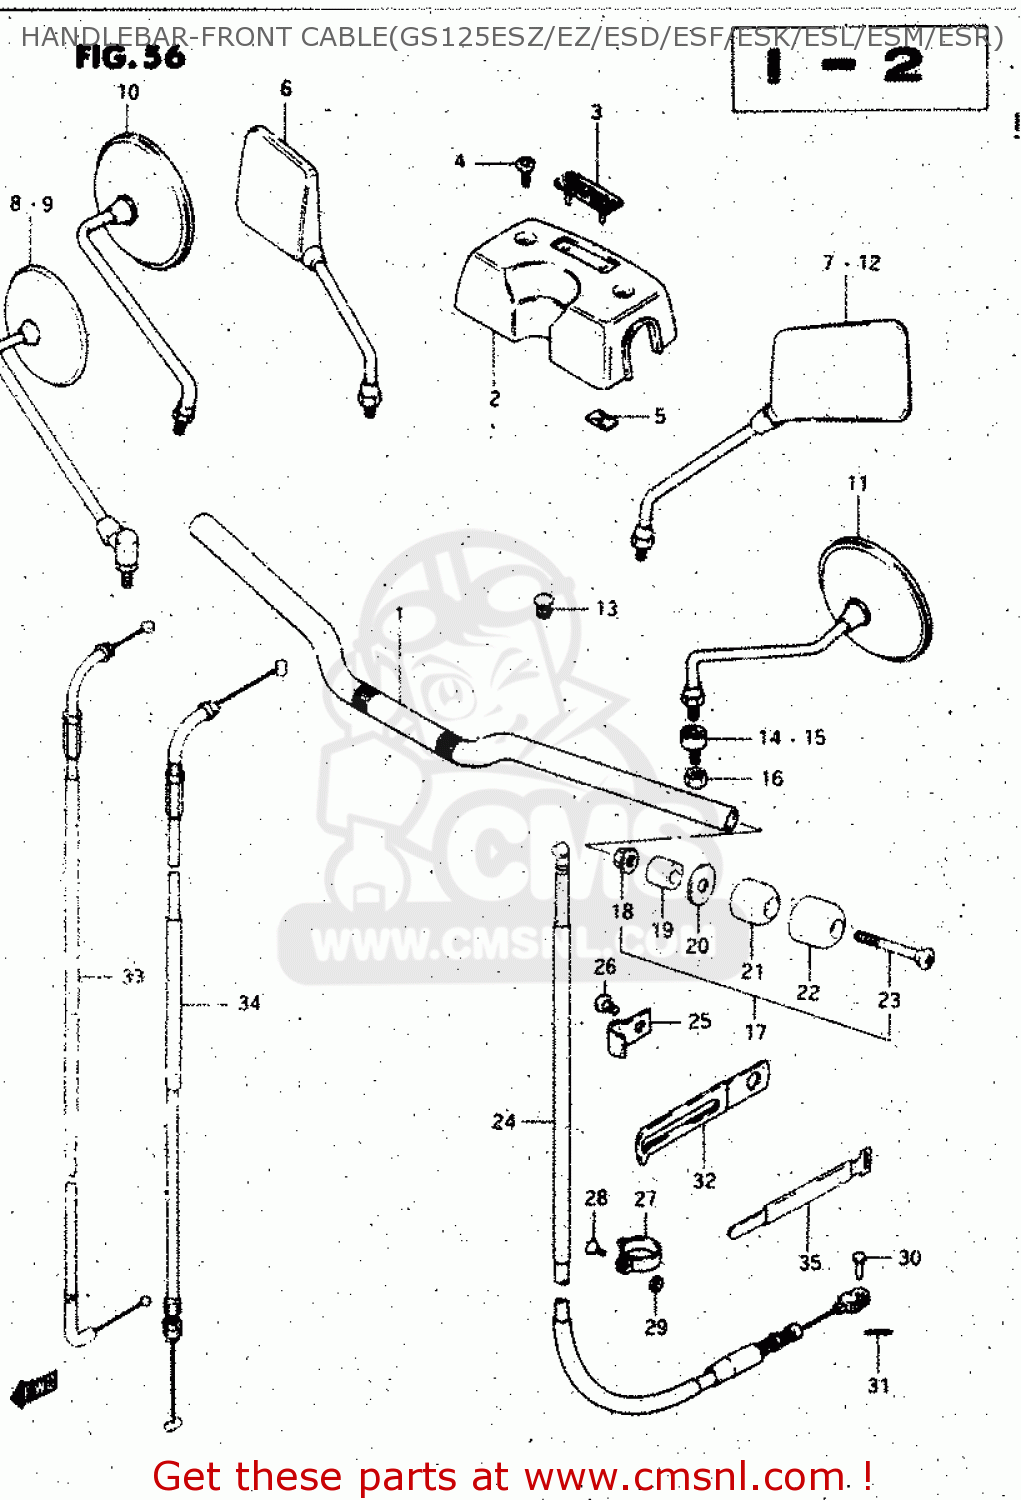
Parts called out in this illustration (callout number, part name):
1	HANDLEBAR
2	COVER,STEERING HEAD
3	EMBLEM,HANDLE COVER PAD
4	SCREW(6X16)
5	NUT
6	MIRROR ASSY, REAR VIEW RH
7	MIRROR ASSY, REAR VIEW LH
8	MIRROR ASSY,RR VIEW
9	MIRROR ASSY,RH
10	MIRROR ASSY, REAR VIEW RH
11	MIRROR ASSY, REAR VIEW LH
12	MIRROR ASSY, REAR VIEW LH
13	CAP(OD:14)
14	CUSHION ASSY,RR VIEW MIRROR
15	CUSHION,REAR VIEW MIRROR
16	NUT
17	BALANCER SET,HANDLEBAR
18	NUT
19	EXPANDER,HANDLE BALANCER
20	SPACER,BALANCER
21	BALANCER,HANDLE
22	CAP,BALANCER
23	SCREW
24	CABLE ASSY,CLUTCH
25	CLAMP,CLUTCH CABLE NO.1
26	SCREW
27	CLAMP,CABLE
28	SCREW
29	NUT
30	PIN(L:15)
31	PIN
32	CLAMP
33	CABLE ASSY,THROTTLE
34	CABLE ASSY,THROTTLE
35	CLAMP
